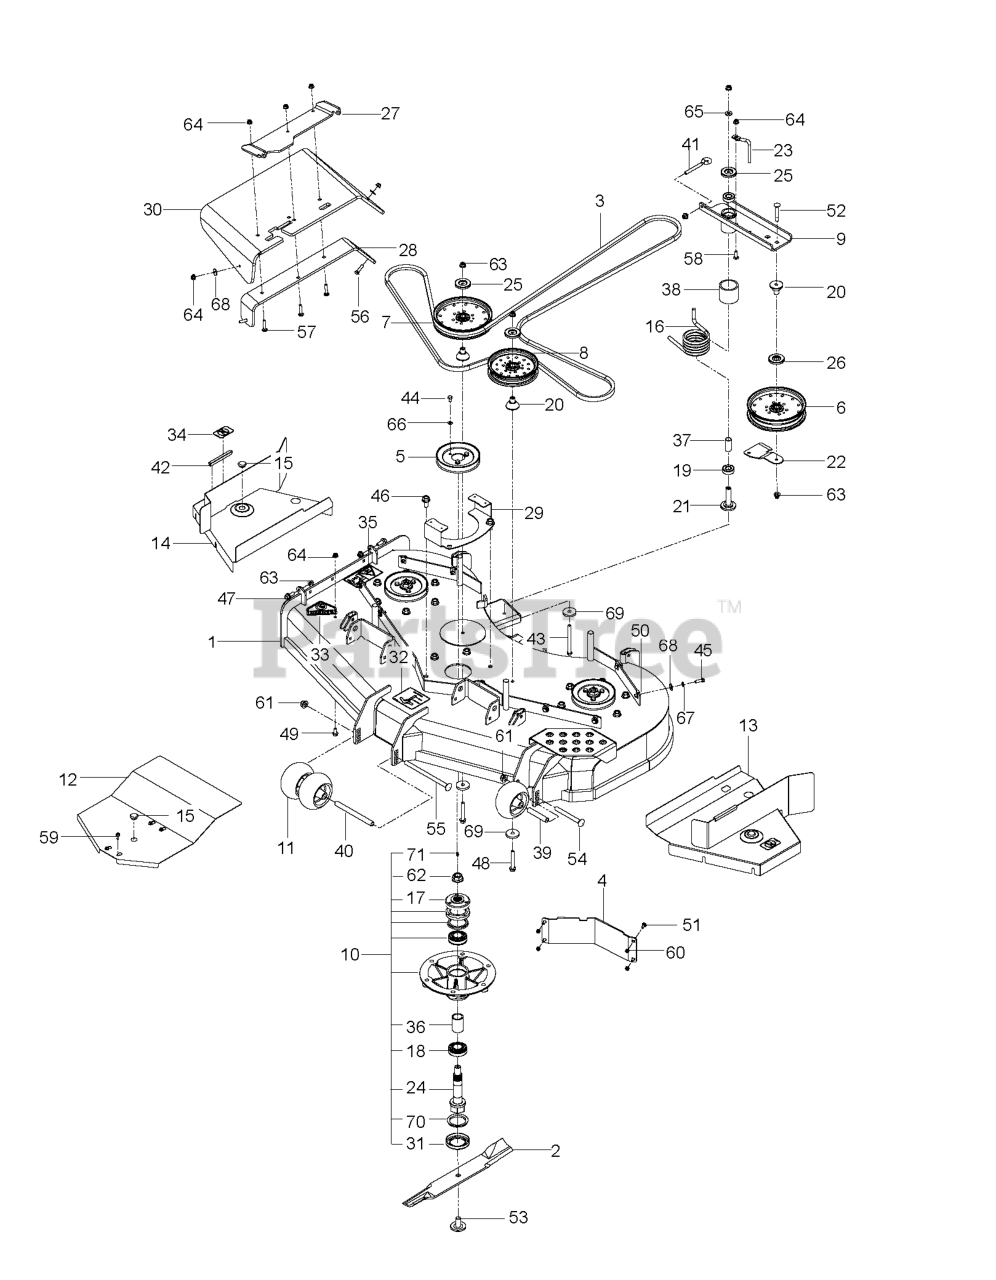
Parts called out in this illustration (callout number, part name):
1	WELDMT, 54" DECK ORANGE
2	BLADE, 19"
3	RP_BELT, "5V", 169.75"
4	BAFFLE, DIVERTER 54"/60" LH
5	PULLEY - 5.93 OVER PINS
6	PULLEY - IDLER 7"
7	PULLEY - 7" NARROW
8	PULLEY IDLER, 6" NARROW
9	IDLER.ARM.BLACK
10	SPINDLE ASM. 10"
11	ROLLER, GAUGE .635 BORN
12	GUARD CENTER.PZG54.BLK
13	WELDMENT.LH.PZG54.BLK
14	WELDMENT.RH.PZG54.BLK
15	PLUG, BUTTON HOLE
16	SPRING, TORSION, IDLER
17	HUB - PULLEY
18	BEARING - 206KRR8
19	BEARING, BALL
20	BEARING, IDLER ARM
21	BEARING, IDLER PIVOT
22	BELT.GUIDE.BLACK
23	BELT KEEPER
24	SHAFT - SPINDLE
25	DUST SHIELD
26	SHIELD, DUST
27	BRKT - CHUTE MTG BLACK
28	BRKT, CHUTE SUPPORT BLACK
29	BRACKET GUARD.PZG.BLK
30	CHUTE, DISCHARGE 48-52
31	CUP - DEBRIS
32	DECAL, BELT ROUTING
33	DECAL, CPSC
34	DECAL, NO STEP
35	DECAL, EURO SEVERING
36	SPACER - BEARING
37	SPACER, IDLER BEARINGS
38	SPACER, IDLER PIVOT
39	TUBE, ROLLER AXLE
40	TUBE, ROLLER AXLE LONG
41	EYE BOLT, 3/8 X 4"
42	RP.FLEX TRIM, BLK-LENGTH 1 FT
43	HCS 3/8-16 X 4-1/2 GR 8 ZD
44	HCS 5/16-18 X 1/2 GR 5 ZD
45	HCS 1/4C X 1
46	HHFS 1/2-13 X 1 GR5 ZD
47	HHFS 3/8-16 X 1 GRD 5 ZD
48	HHFS 5/16-18 X 3 3/4
49	HHFS 5/16-18 X 3/4
50	U-CLIP 5/16-18 NUT RETAINER
51	1/4-20X3/4 CARR BLT
52	CARRIAGE BOLT 3/8-16 X
53	BLADE BOLT/WASHER
54	RHSNB 1/2-13 X 4.75 GR5 ZD
55	RHSNB 1/2-13 X 8 GR5 ZD
56	BOLT, CARRIAGE 5/16X1-1/4
57	RHSNB 5/16-18 X 1-1/2 GR 5 ZD
58	RHSNB 5/16C X 1
59	SCREW- 1/4-20 X 5/8
60	NUT.1/4-20.HEX.NYLOC.ZD
61	NUT, 1/2-13 HEX FLG NYLOC ZD
62	NUT FLANGE 3/4-16
63	NUT 3/8-16 HEX FLG NYLOC ZD
64	5/16-18 NYLOC FLANGE NUT
65	WASHER, 3/8 THICK
66	WASH 5/16 DISC SPRING ZD
67	WASHER.LOCK.HVY.HLCL.SPR.5/16
68	WASHER 5/16 FLAT
69	SPINDLE WASHER
70	V-RING, 55MM
71	ZERK
